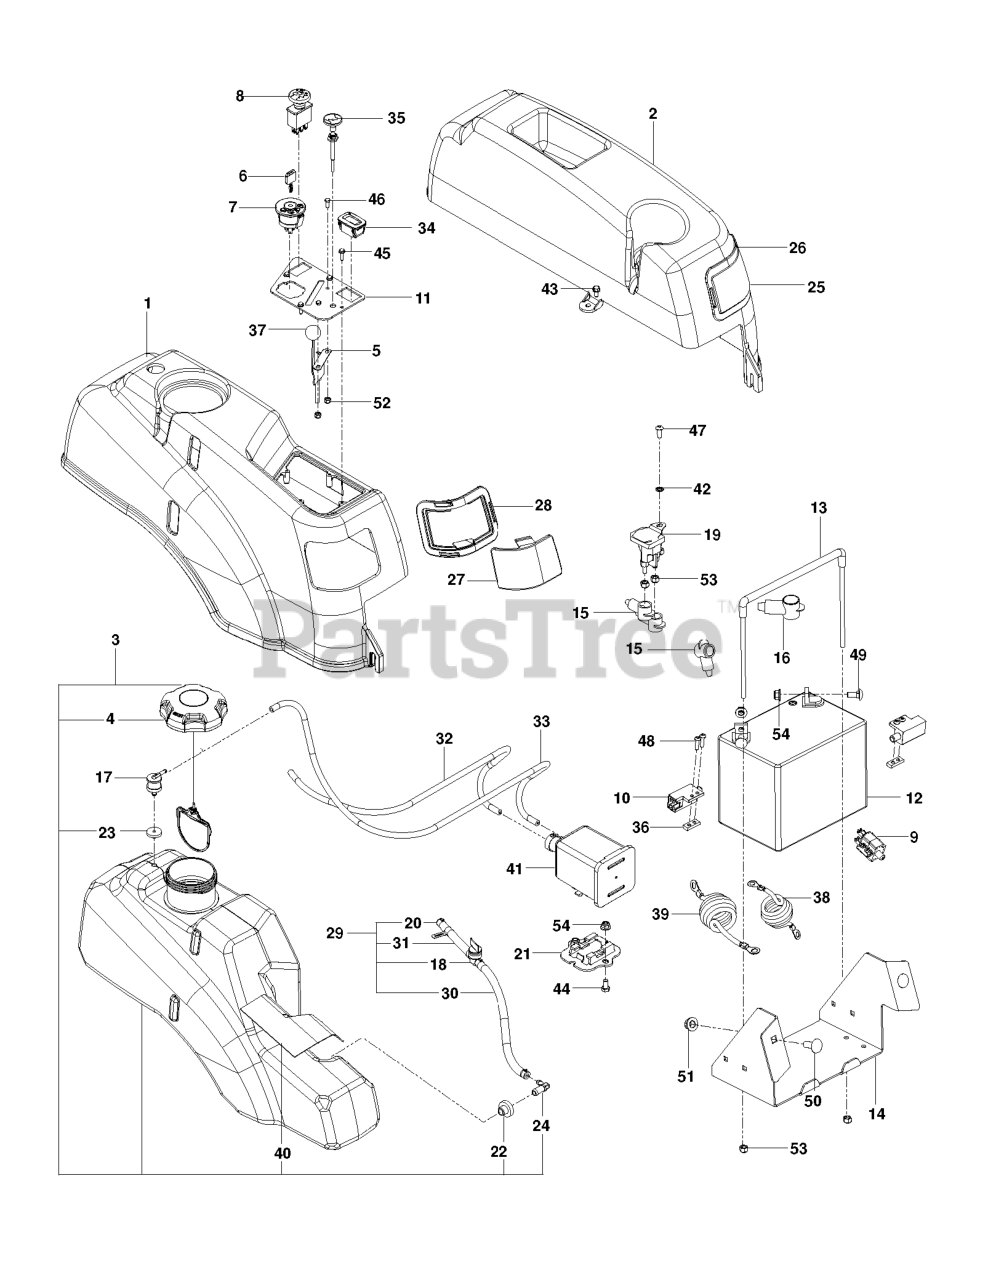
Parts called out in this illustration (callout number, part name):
1	FENDER, RT, GRAY
2	FENDER, LT
3	TANK.FUEL.ASSEMBLY.LARGE
4	CAP, FUEL
5	THROTTLE CABLE
6	KEY MLD GEN DELTA
7	RP IGNITION SWITCH
8	RP SWITCH.PTO.8.TERMINAL.RED
9	SWITCH, BRAKE 3P
10	SWITCH INTERLOCKT
11	CONSOLE.PLATE.BLACK
12	BATTERY, 12 V 330 AMP
13	BATTERY TIE DOWN ASSEMBLY
14	BOX, BATTERY, BLACK
15	TERMINAL COVER-SM
17	VALVE.FUEL.CHECK
18	FUEL VALVE
19	SOLENOID.W/BRASS.PLUNGER
20	HOSE CLAMP
21	BRACKET, CANISTER
22	RUBBER GROMMET
23	GROMMET, CHECK VALVE
24	STEM, FUEL TANK
25	LENS, COLORED LEFT
26	LEFT HEADLIGHT RIM GREY
27	LENS, COLORED RIGHT
28	RT HEADLIGHT RIM GREY
29	FUEL LINE ASSY
30	GAS LINE 10"
31	FUEL LINE 3"
32	FUEL LINE 33"
33	HOSE, VAPOR 3/16 X 39"
34	RP.GUAGE.SRVCMNDR.HRMTR.
35	CHOKE CABLE
36	TAPPED PLATE
37	KNOB.ROUND.BALL.BLACK
38	CABLE POSITIVE, LONG
39	BATTERY CABLE, NEGATIVE
40	SHIELD, HEAT
41	CANNISTER, CARBON
42	WASHER 1/4 INT TOOTH
43	SCREW
44	HCS 5/16-18 X 5/8 GR 5 ZD
45	SCR #10-12X3/4 HEX WAS HD ZD
46	HCS #10-24 X 1/2
47	SCR 1/4-20 X 5/8 BTN SKT HD ZD
48	SCR #10-24 X .75 SKT HD BLK
49	RP BOLT 5/16-18 X3/4 ZN/YEL GR
50	RHSNB 3/8C X 1
51	NUT 3/8-16 HEX FLG NYLOC ZD
52	NUT 10-24 NYLOC
53	NUT.1/4-20.HEX.NYLOC.ZD
54	5/16-18 NYLOC FLANGE NUT
